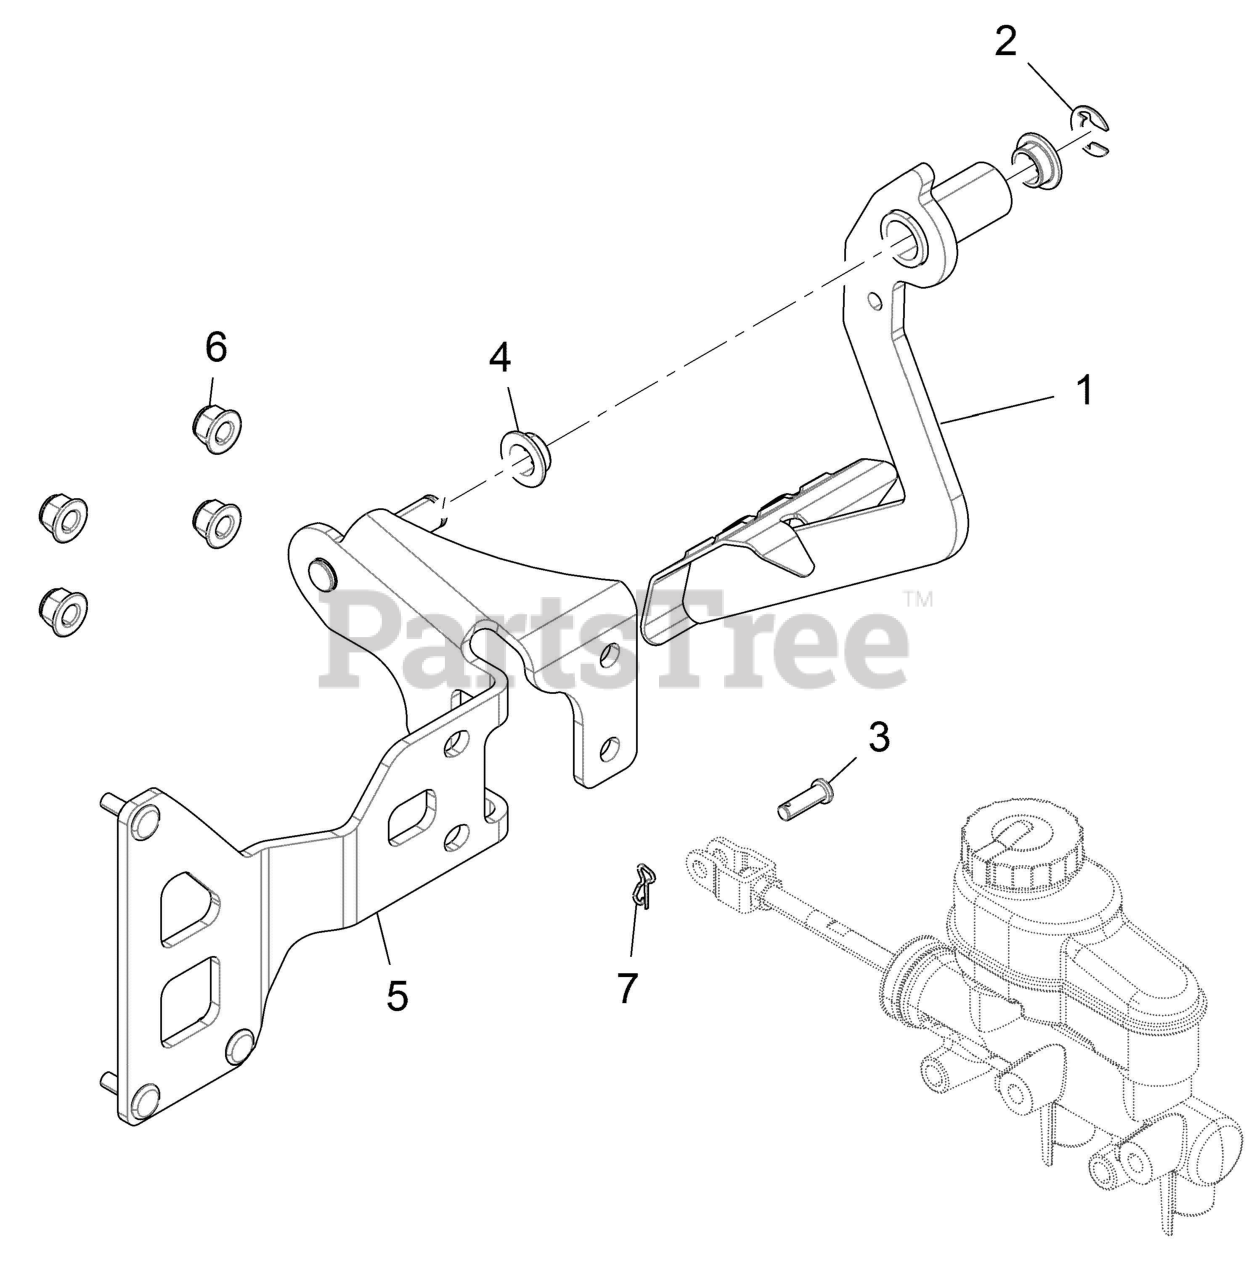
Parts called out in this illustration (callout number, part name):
1	WELD-BRAKE PEDAL,MATTE'BLK
3	PIN-CLEVIS, 1/4 X 3/4 -Y
4	BUSHING-PEDAL PIVOT
5	MOUNT, PEDAL, BLACK
6	NUT-M8X1.25,FLG,NYLOC-OLIVE D
7	PIN-CLIP,14MM
